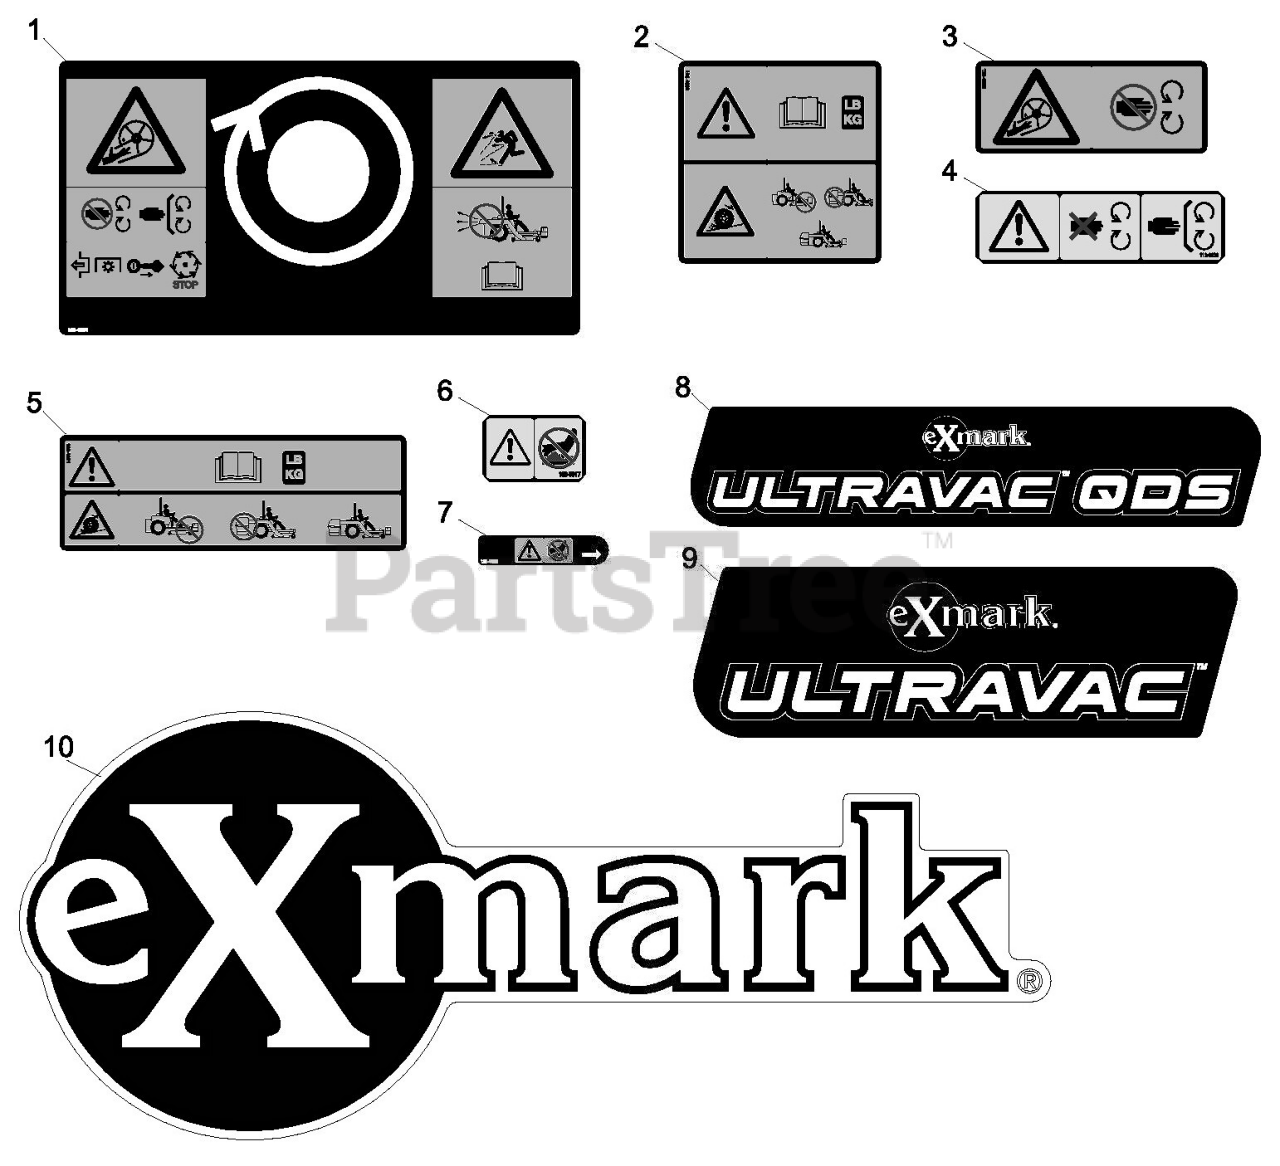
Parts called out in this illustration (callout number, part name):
1	Decal-Warning Blower
2	DECAL-WARNING, TRACTION
3	Decal-Blower Impeller Hazard
4	DECAL-COVER, MISSING
5	DECAL-WARNING WEIGHT
6	DECAL-WARNING
7	DECAL-WARNING
8	Decal, UltraVac QDS
9	Decal, UltraVac
10	DECAL-EXMARK LOGO
